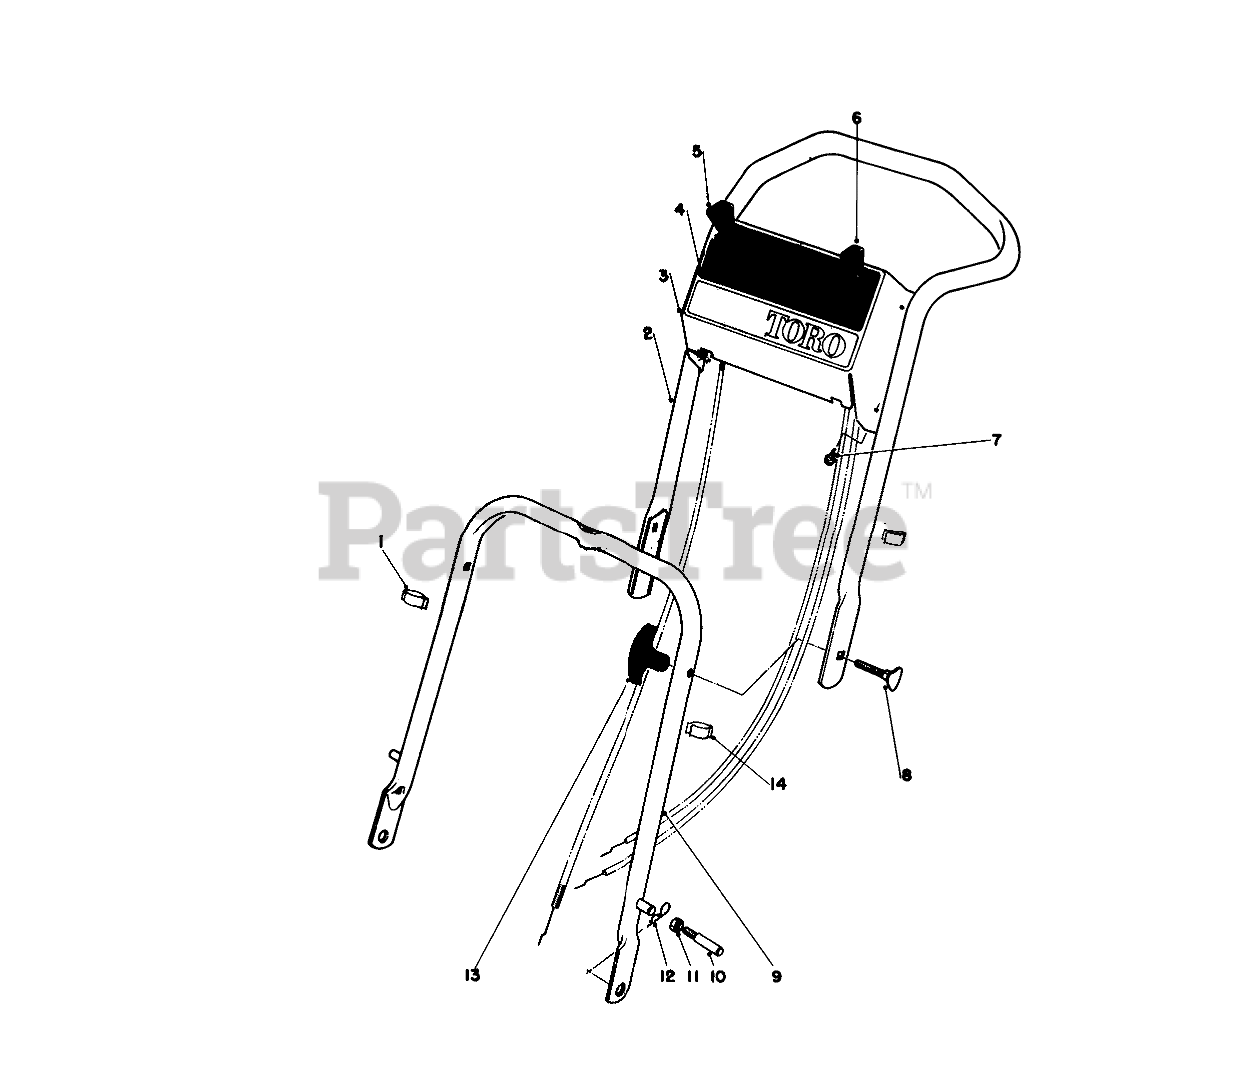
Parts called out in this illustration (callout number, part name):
2	UPPER HANDLE
3	Control Plate
4	Decal-Control Plate
5	Throttle Control
6	Traction Control
7	SCREW-HWHTF
8	HANDLE SCREW
9	LOWER HANDLE ASM
10	HANDLE PIN
11	Nut
12	PIN-COTTER, HAIR
14	BOWDEN CLIP
